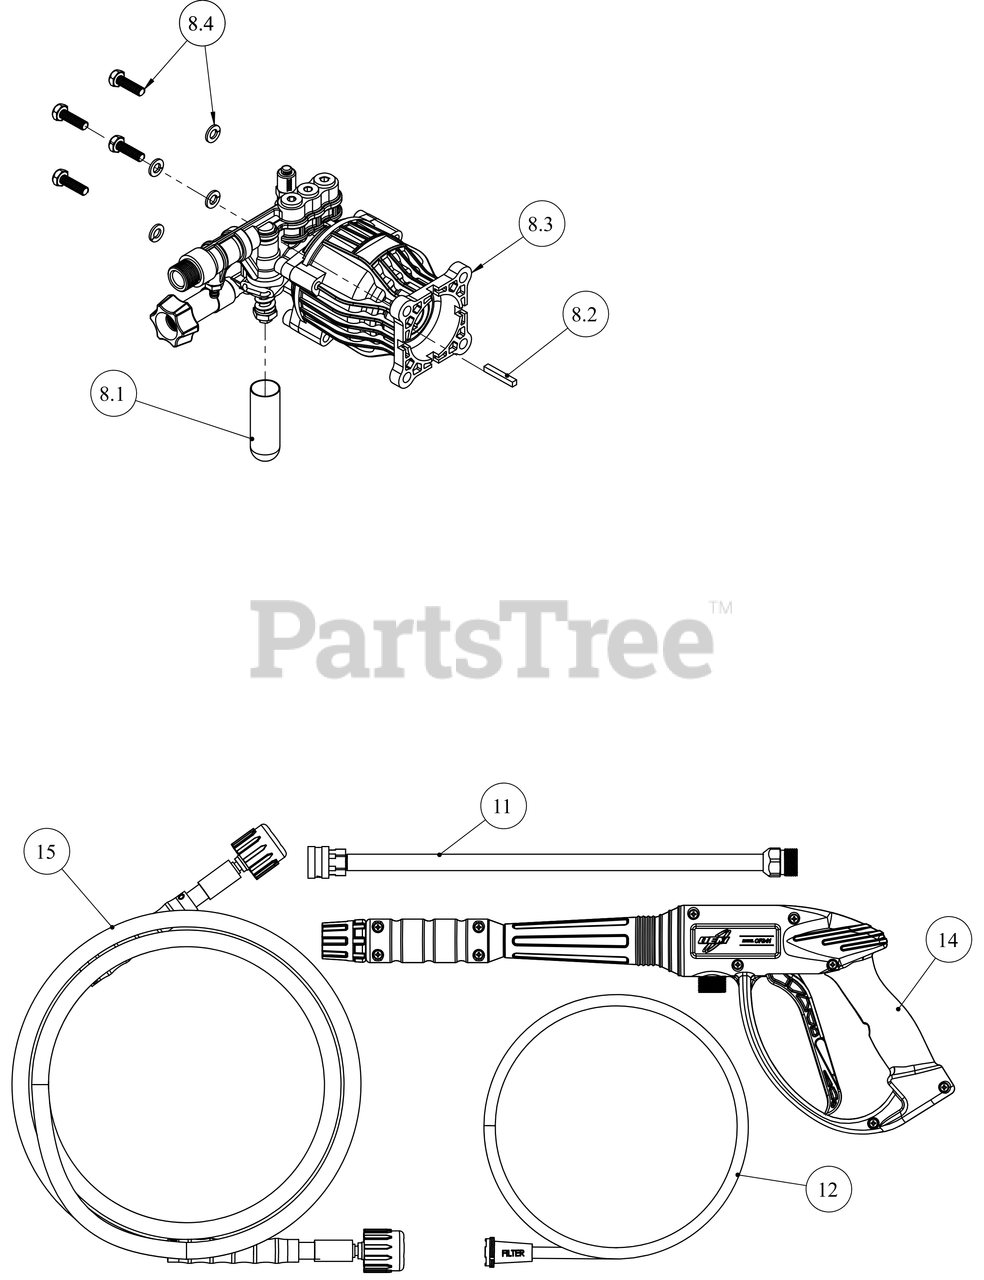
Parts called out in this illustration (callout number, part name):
8	PUMP (SVC 520006)
8.2	SHAFT KEY (3/16x3/16x1.25)
8.3	PUMP HEAD
8.4	HARDWARE KIT: PUMP MOUNTING
11	WAND-SPRAY GUN 16"
12	HOSE-SOAP W/FILTER
14	SPRAY GUN FRONT ENTRY
15	SPRAY GUN HOSE 25'
